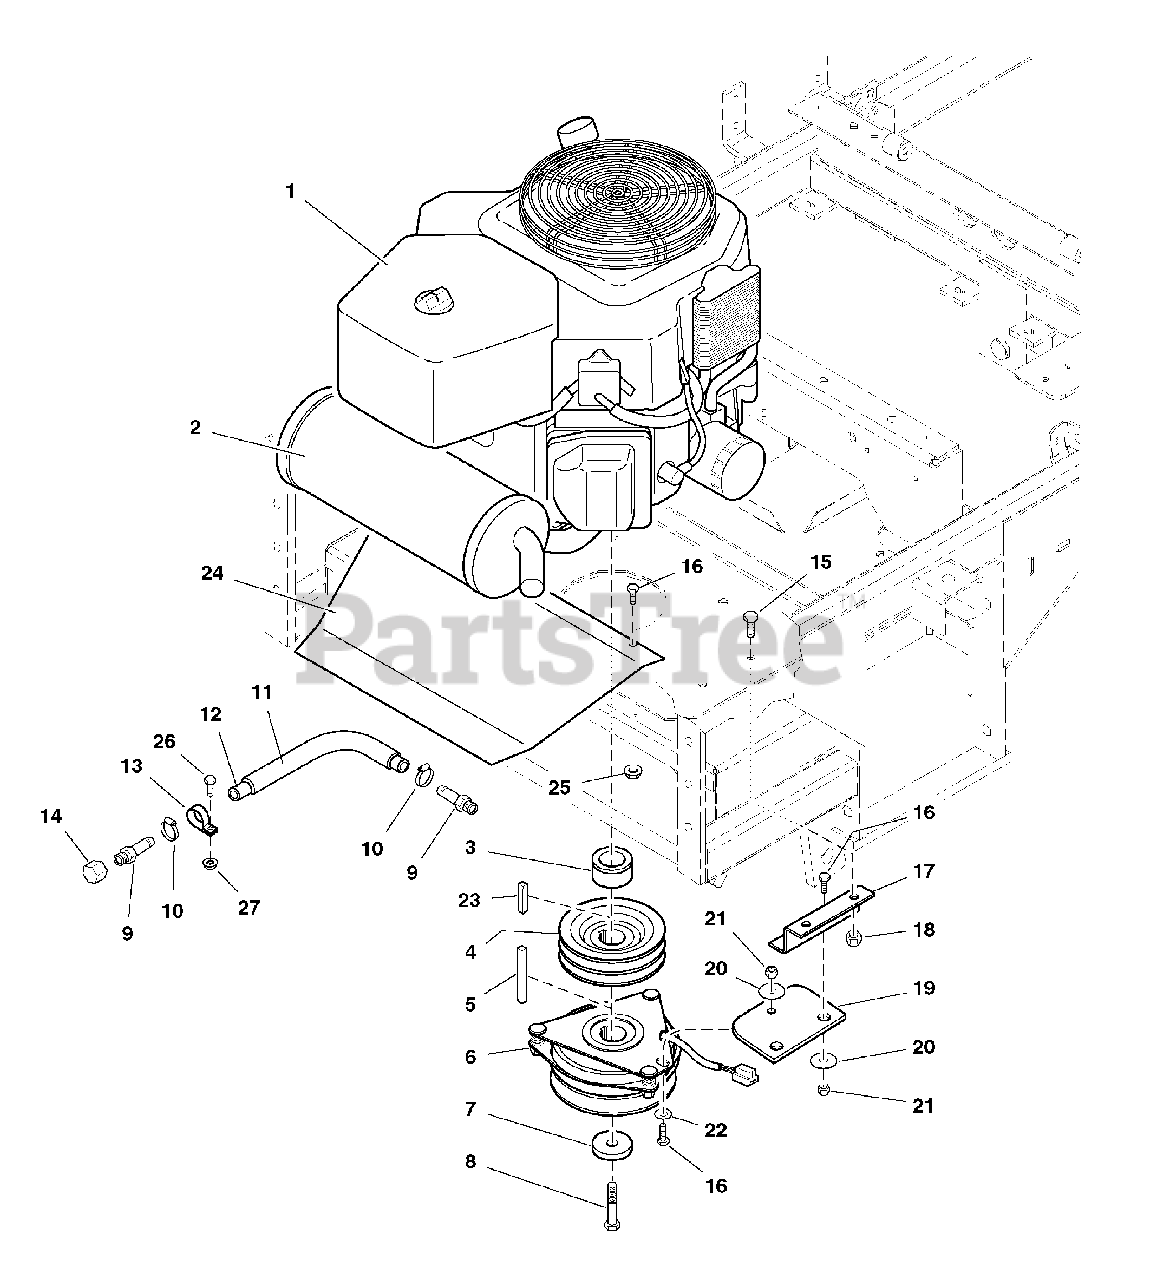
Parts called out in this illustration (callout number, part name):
1	ENGINE, 25HP Kohler
3	CRANKSHAFT SPACER
4	CRANKSHAFT PULLEY
5	KEY, 1/4 Sq. x 2-1/2
6	ELECTRIC CLUTCH
7	RETAINER, Clutch
8	CRANKSHAFT BOLT, 7/16 x 1-3/4
9	FITTING, 3/8NPT - 1/2 Str.
11	WIRE LOOM, 12"
13	CLAMP, Vinyl
14	CAP, 3/8NPT
15	CAPSCREW, Hex Hd, 3/8-16 x 1
16	CAPSCREW, Hex Hd, 5/16-18 x 3/4
17	ANCHOR, CLUTCH - BLK
18	NUT, Hex, Nylon Lock, 3/8-16
19	PAD, Clutch Anchor
20	WASHER, Fender, 5/16
21	NUT, Hex, Nylon Lock, 5/16-18
22	WASHER, 5/16
23	KEY, 1/4 Sq. x 1
24	HEAT SHIELD
25	NUT, Hex, Serrated Flange, 5/16-18
26	CAPSCREW, Hex Hd, 1/4-20 x 3/4
27	NUT, Hex, Serrated Flange, 1/4-20
